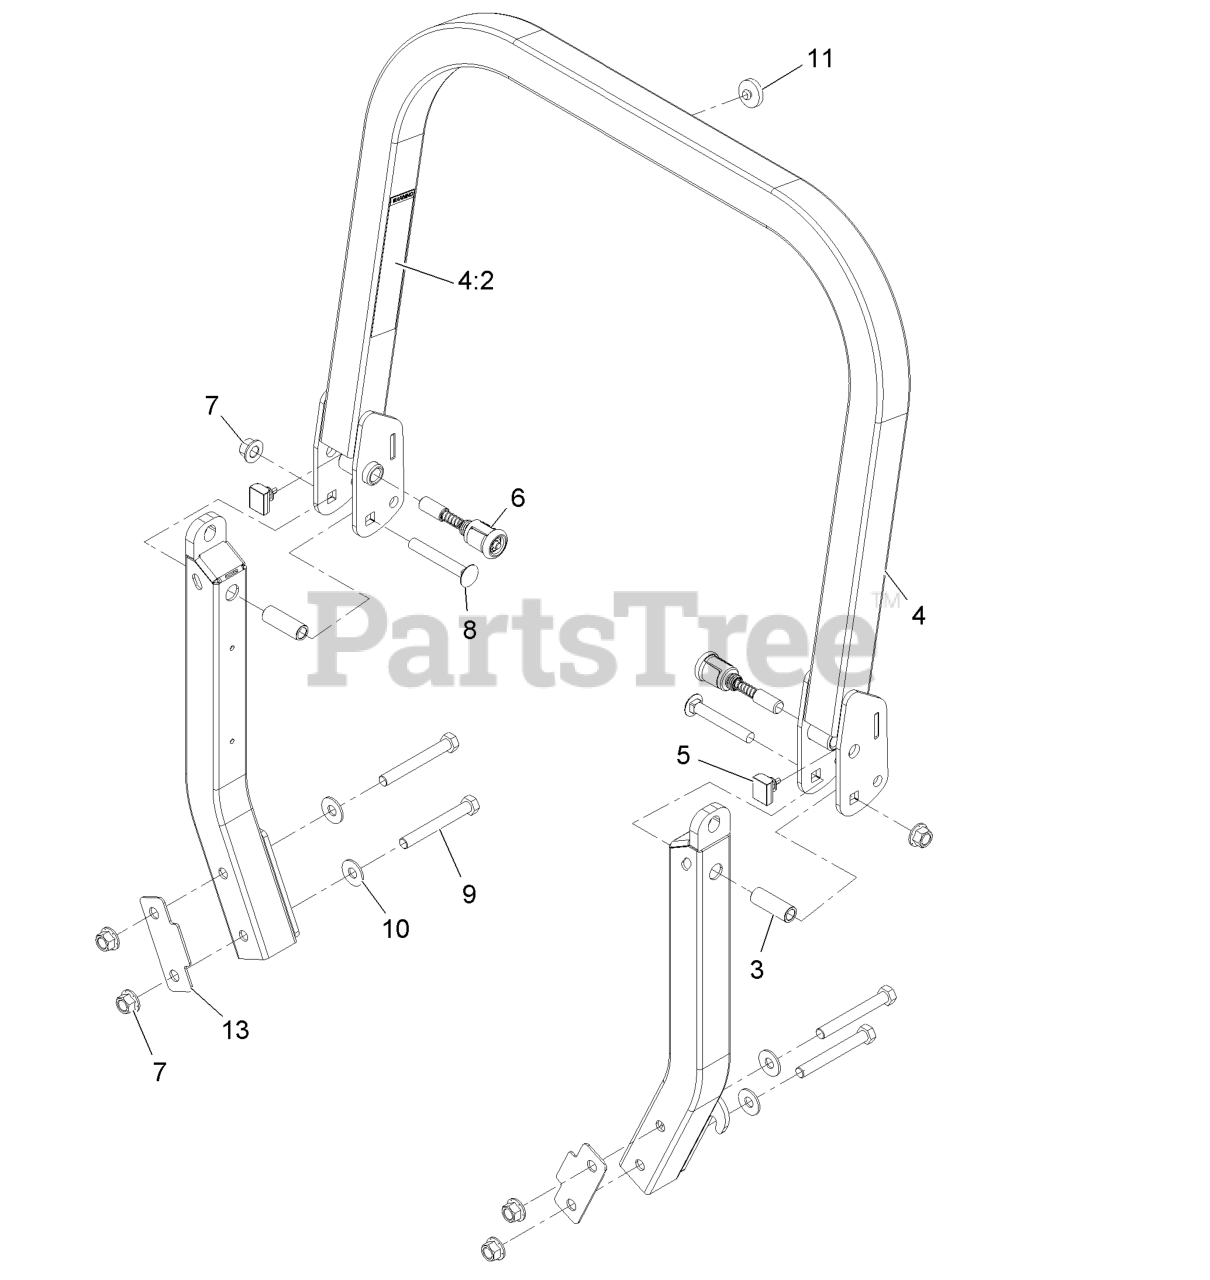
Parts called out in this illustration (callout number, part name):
4	UPPER ROPS ASM
4:2	DECAL-WARNING, FOLDING RO
5	BUMPER-ROPS
6	PIN-SPRING
7	Nut-Lock 1/2-13
8	SCREW-CARR
9	SCREW-HH
10	WASHER-SPRING
11	BUMPER-PUSH-IN, RUBBER
